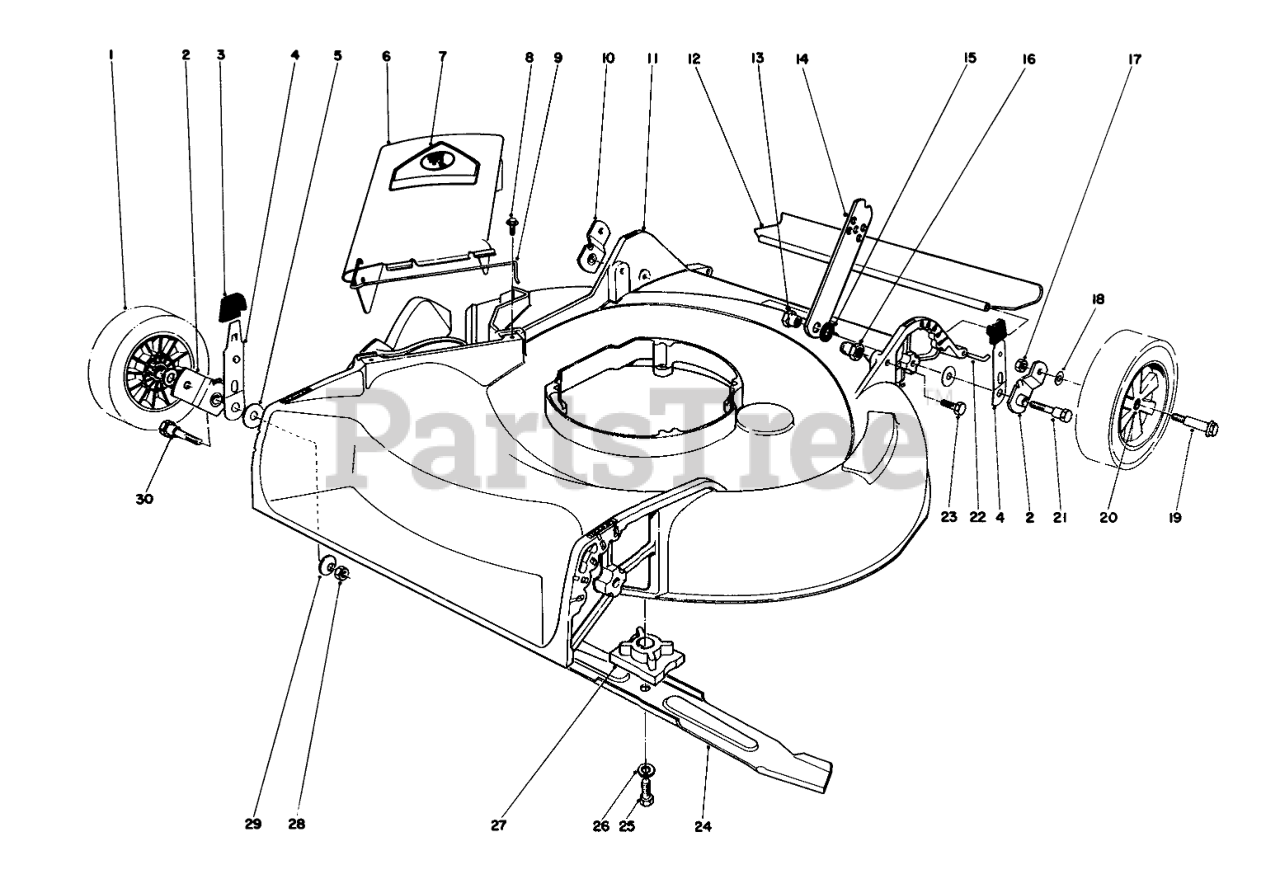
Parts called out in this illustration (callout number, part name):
1	Wheel & Tire Assembly (Incl. Ref. #20)
2	Pivot Arm
3	KNOB-ARM
4	SPRING ARM ASM
5	WASHER-PIVOT
6	Deflector Assembly (Incl. Ref. #7 & 10)
7	DECAL-DANGER
8	SCREW-HWH
9	SPRING HINGE
10	Pivot Arm
11	Housing (Incl. Ref. #8)
12	REAR SAFETY SHIELD 21
13	HANDLE PIVOT NUT
14	HANDLE LATCH
15	SPACER
16	HANDLE PIVOT NUT
17	Nut
18	WASHER
19	BOLT-WHEEL
20	BUSHING
21	PIVOT SCREW
22	SHIELD ROD
23	SCREW-HH
24	Blade
25	SCREW-HH
26	WASHER-LOCK
27	BLADE RETAINER
28	NUT-LOCK, NI
29	WASHER-BELLEVILLE
30	5/16-18 PIVOT SCREW
